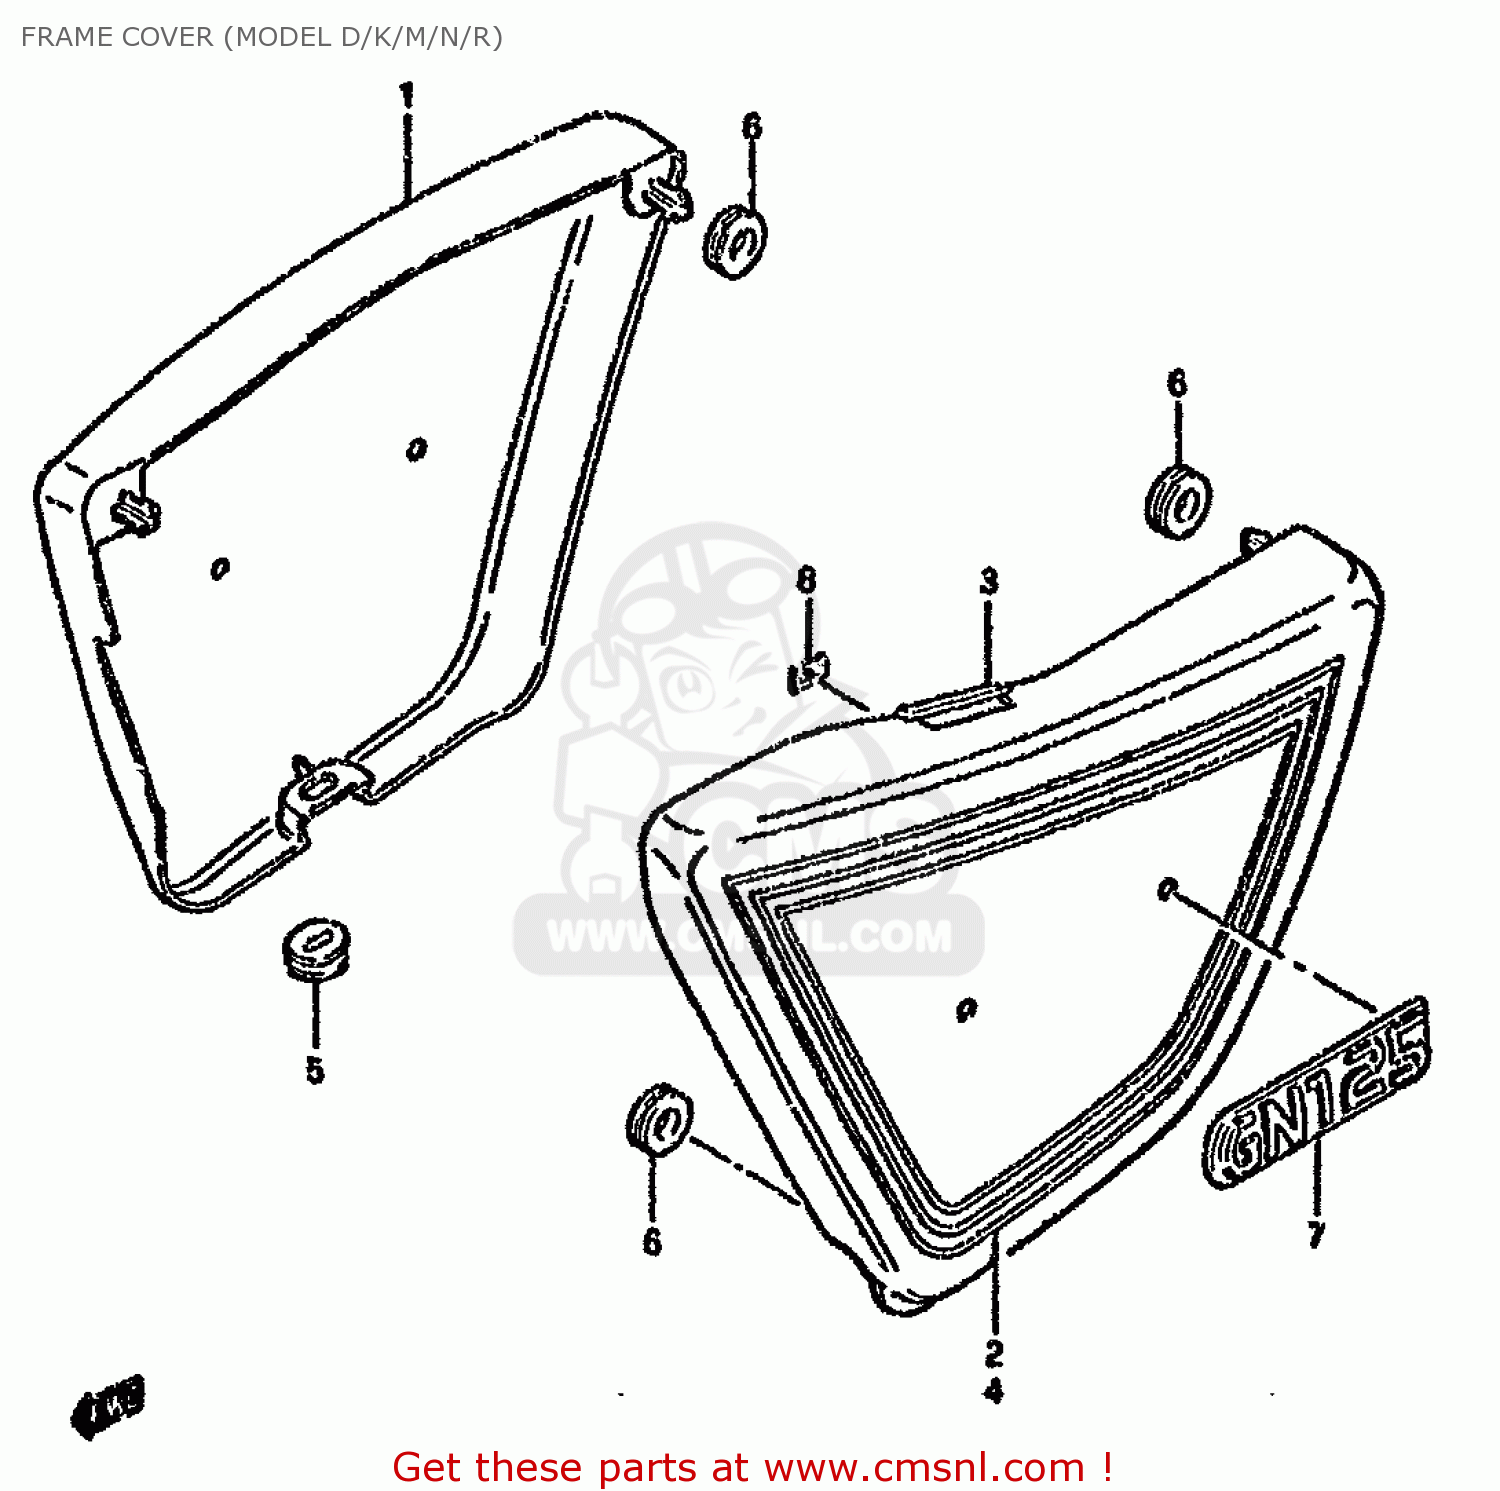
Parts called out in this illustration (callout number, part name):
1	COVER,FRAME,RIGHT
2	TAPE SET,FRAME COVER
3	COVER,FRAME,LEFT
4	TAPE SET,FRAME COVER
5	CUSHION
6	CUSHION
7	EMBLEM,FRAME COVER
8	NUT
